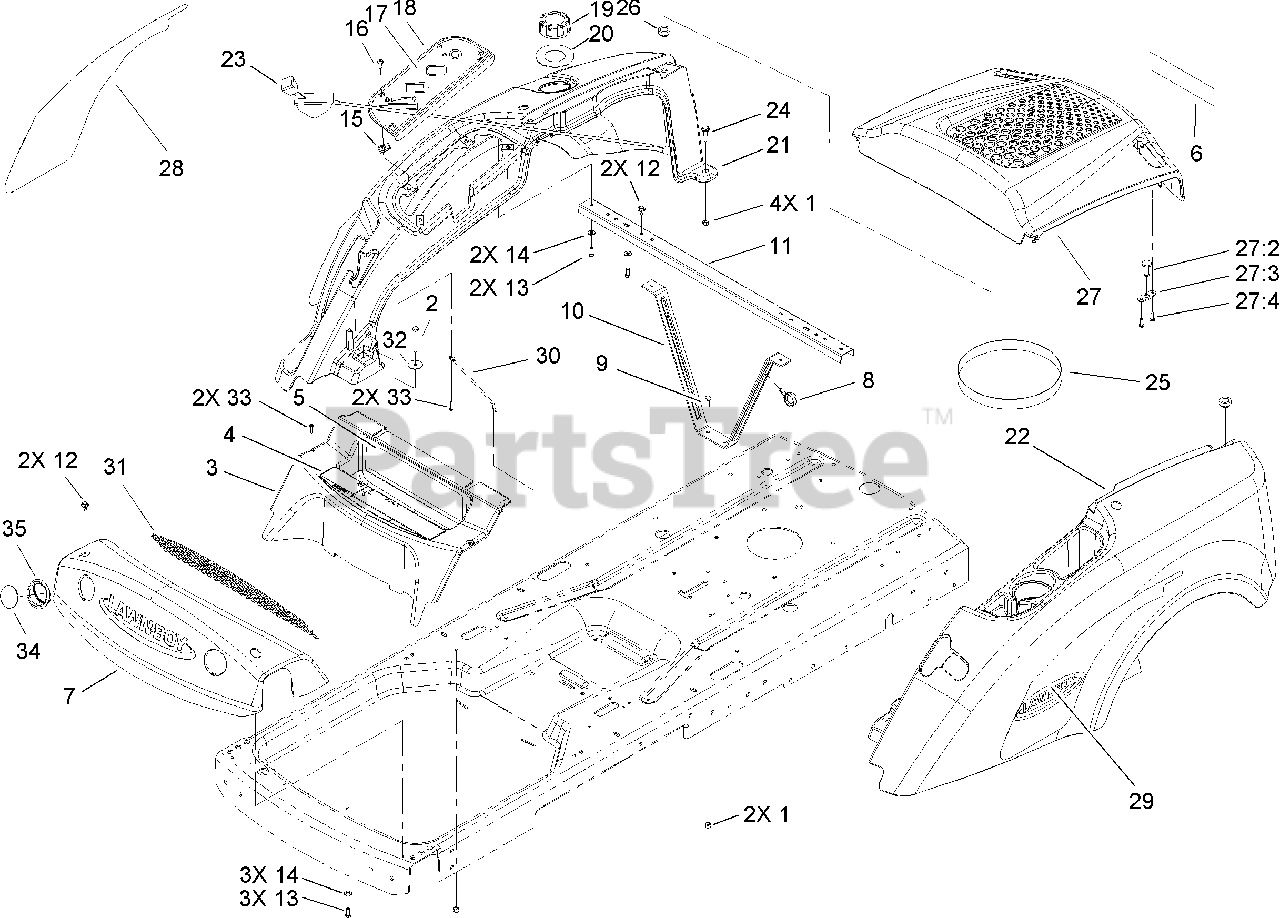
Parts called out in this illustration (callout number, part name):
1	NUT-LOCK, NI
2	SCREW-HH
3	PANEL-KICK
4	DECAL-DANGER
6	DECAL
8	CLAMP-HOSE
9	SCREW-HH
10	BRACE-SUPPORT
11	CHANNEL-CROSS
12	SCREW-HHF
13	SCREW-PLASTITE
14	WASHER-FLAT
16	SCREW-PRH
18	PANEL-CONTROL
19	GAS CAP ASM
20	WASHER-SEAL, RUBBER
21	COVER-SIDE, RH
22	COVER-SIDE, LH
23	CABLE-THROTTLE
24	SCREW-SHOULDER
25	EXTENDER-PLENUM
27	HOOD COVER ASM
30	ROD-SUPPORT
31	FOOTMAT-FOOTREST
32	WASHER-FLAT
33	SCREW-PPH
34	DISK-REFLECTOR
35	BEZEL-RUBBER
